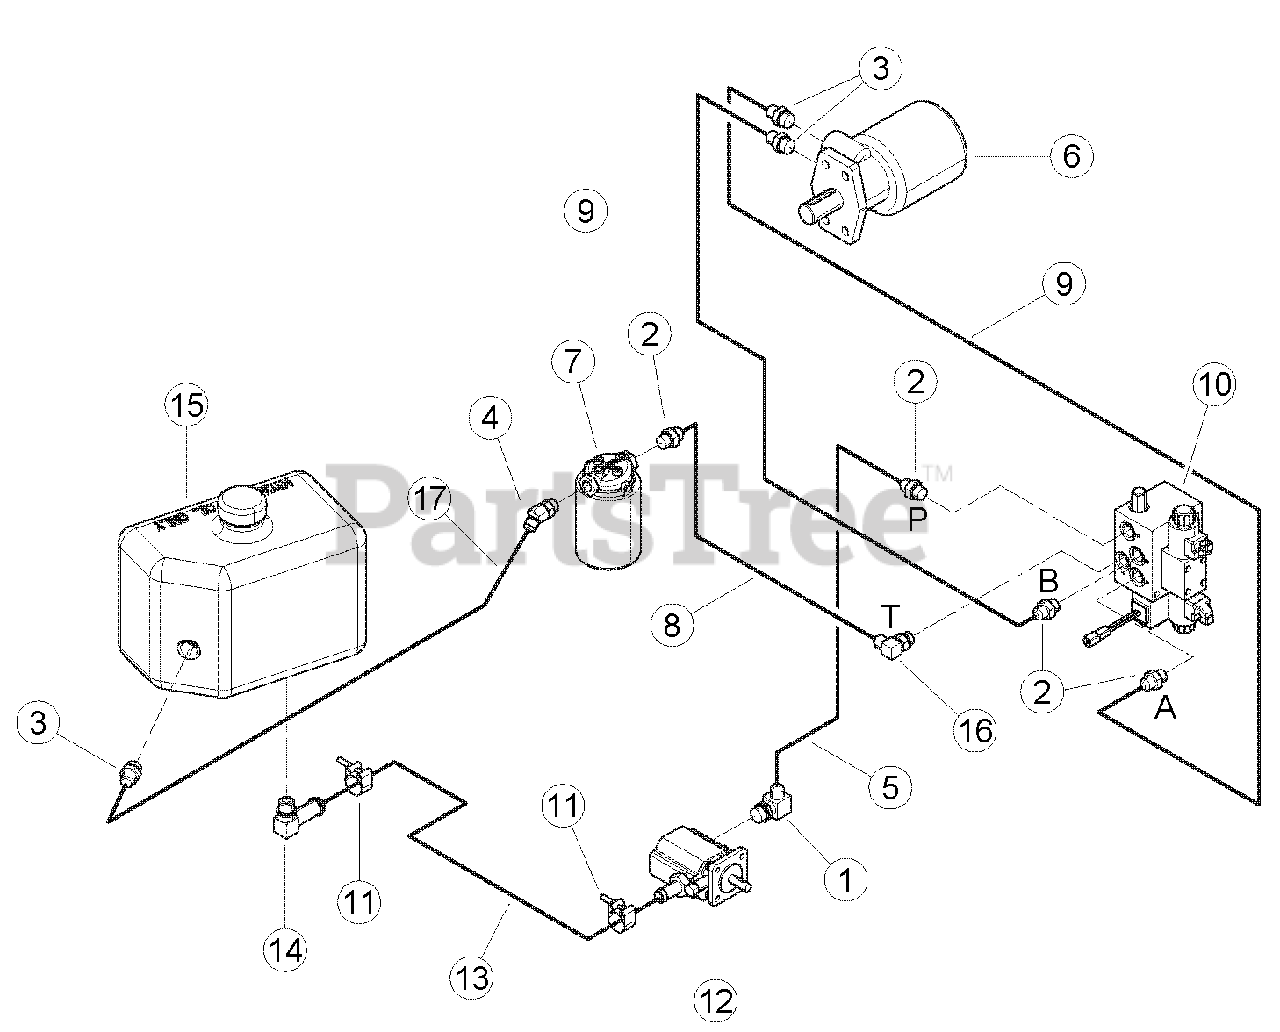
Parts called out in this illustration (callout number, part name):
1	ADAPTER, -10 MORING / -8 MJIC 90 DEG.
2	ADAPTER, -8 MORING / -8 MJIC
3	ADAPTER, -10 MORING / -8 MJIC
4	ADAPTER, -8 MORB / -8 MJIC 45 DEG.
5	HOSE ASSY', -8 FMJIC / -8 FMJICSW X 8-1/2
6	MOTOR, 45 CU. IN. HYDRAULIC
7	FILTER, SPIN ON
8	HOSE ASSY', -8 FMJIC / -8 FMJIC 90 X 21 IN.
9	HOSE ASSY', -8 FMJIC / -8 FMJIC 90 X 61 IN.
10	ASSEMBLY, CHIPPER FLOW VALVE
11	CLAMP, 1" OD. HOSE T-BOLT
12	PUMP, 2 STAGE CW HI/LO 0.605 DISP.
13	HOSE, .75 ID X 28 IN 100R4 HYD
14	ADAPTER, -10 MORING/.75 90 DEG. HOSE
15	TANK, OIL RESERVOIR
16	ADAPTER, -8 MORING / -8 MJIC 90 DEG.
17	HOSE, 3/8 X 35 -8 FJICSW
